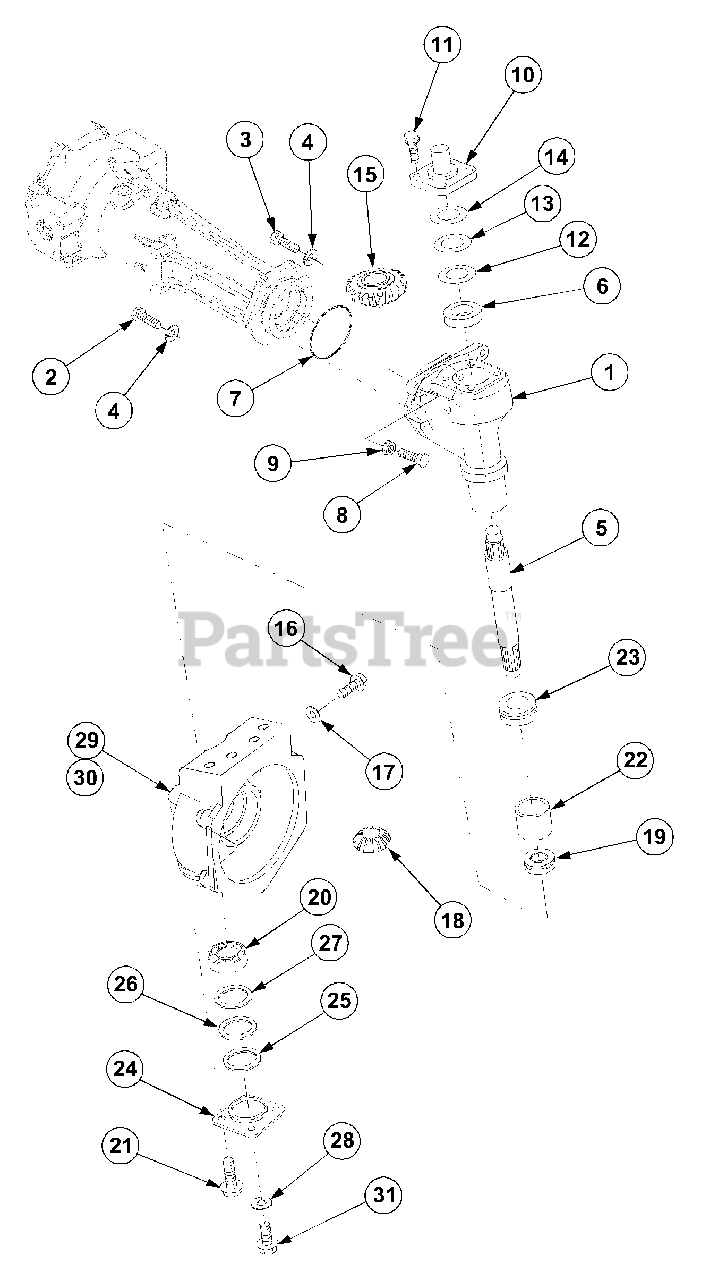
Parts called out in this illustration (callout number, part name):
1	Case,King Pin
4	Washer,Spring
11	Bolt,w/Washer
19	Bearing,Thrust
21	Bolt,w/Washer
29	Case L.H Gear
30	Case R.H Gear
